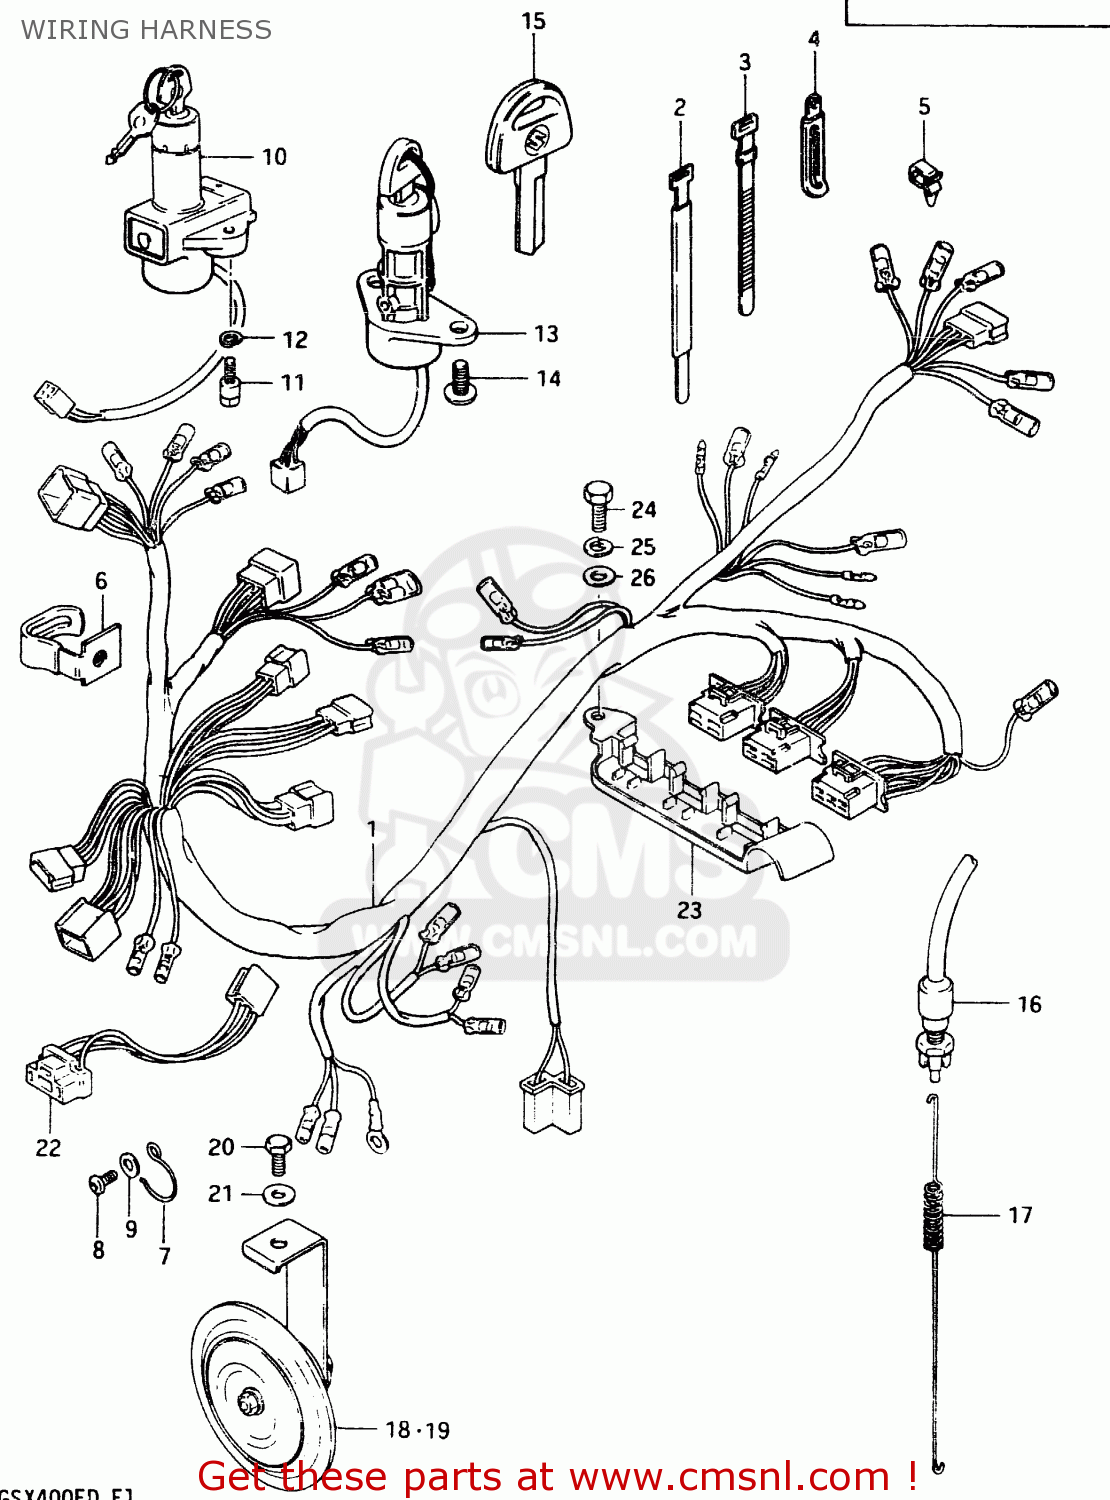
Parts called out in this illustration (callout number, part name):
1	WIRING HARNESS
2	CLAMP
3	CLAMP(L:80)
4	CLAMP
5	CLIP
6	CLAMP,WIRING HARNESS
7	GUIDE,WIRING HARNESS
8	SCREW 6X12
9	WASHER
10	SWITCH ASSY,IGNITION
11	BOLT
12	LOCK WASHER
13	SWITCH ASSEMBLY,IGNITION
14	SCREW 6X12
15	KEY,BLANK
16	SWITCH ASSEMBLY,STOP LAMP
17	SPRING
18	HORN
19	HORN
20	BOLT 8X12
21	WASHER
22	LEAD WIRE,HEADLAMP
23	PLATE, COUPLER
24	BOLT
25	LOCK WASHER
26	WASHER
